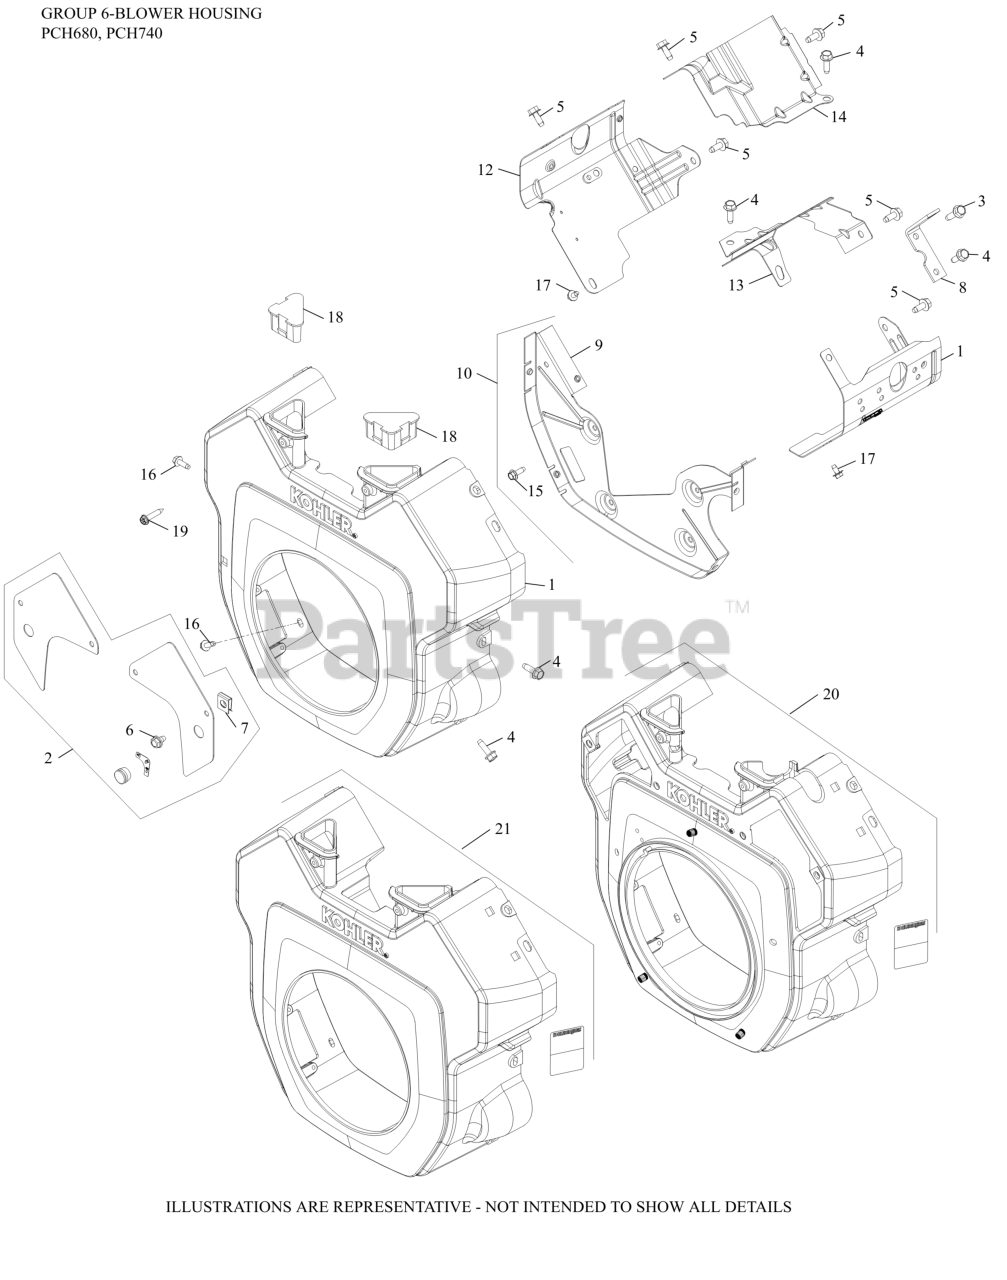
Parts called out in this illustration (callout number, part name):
2	KIT, ACCESS PANEL
3	SCREW, THREAD FORMING
4	SCREW, THREAD FORMING
5	SCREW, THREAD FORMING
6	SCREW, THREAD FORMING
7	CLIP, BAFFLE MOUNTING
8	STRAP, LIFT
9	PLATE, BACKING
10	KIT, BACKING PLATE
11	KIT, RIGHT BARREL
12	BAFFLE LEFT BARREL
14	BAFFLE, VALLEY #2 CYLINDER
15	SCREW, THREAD FORMING
16	SCREW, THREAD FORMING
17	SCREW, THREAD FORMING
18	COVER, BLOWER HOUSING
20	HOUSING, BLOWER
NI	BAFFLE, VALLEY #1 CYLINDER
